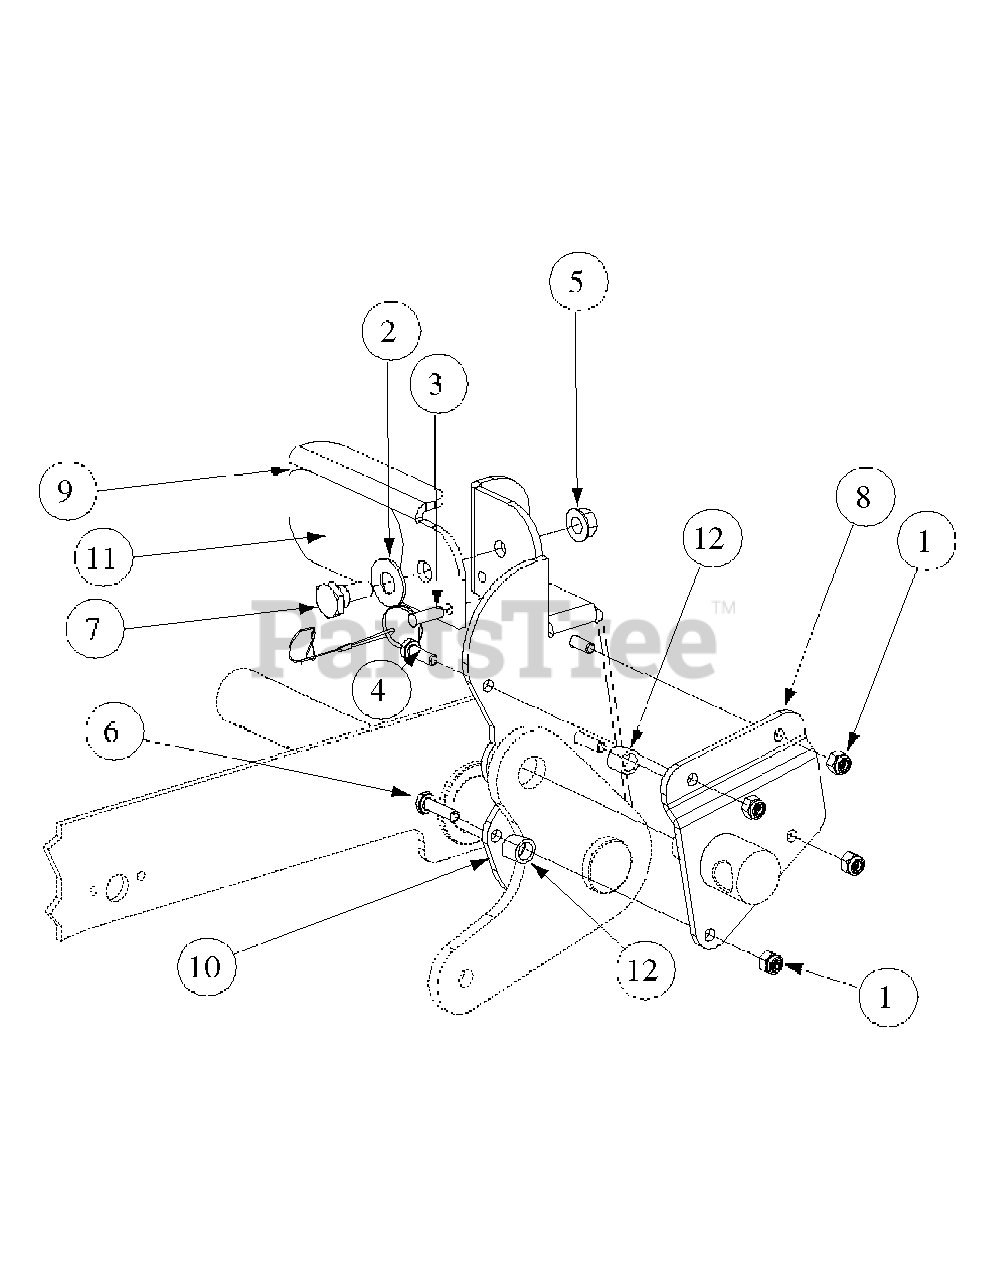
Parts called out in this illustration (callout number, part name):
1	Lock Nut, Nylon Insert, 1/4-20
2	Washer, 1/2 x 1 Shim
3	Detent Pin w/12" Lanyard
4	Hex Cap Screw, 1/4-20, .75
5	Hex Nut, Flange Lock 3/8-16
6	Hex Cap Screw, 1/4-20, 1.00
7	Shoulder Screw, .50 x .27 Lg., 3/8-16
8	Foot Lift Backup Pedal
9	Deck Foot Pedal Lift
10	Deck Foot Pedal Lift
11	Deck Foot Lift Pad
12	Turnbuckle Sleeve
